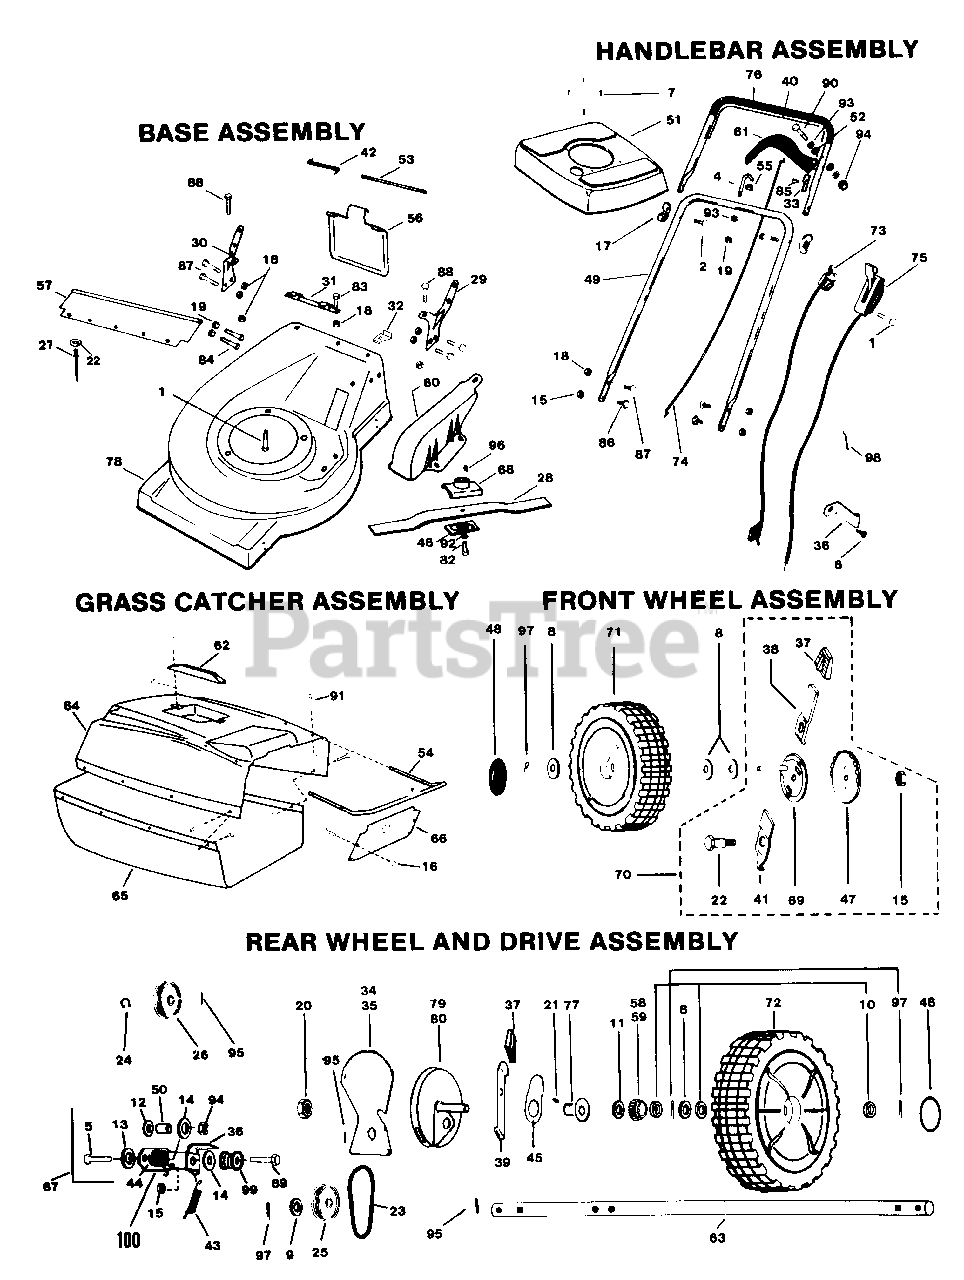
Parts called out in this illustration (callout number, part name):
1	Screw .375-16 x 1.00 Ind. Hex Hd.
2	Saddle Bolt .312-18 x .750
3	Screw .250-20 x .750
5	Screw .250-20 x 1.250
6	Screw #10-32 x .375
7	Screws-Engine Shroud
15	Nut .375-16 Keps
16	Nut #10-32 Keps
18	Nut .312-18 Keps
19	Nut .250-20 Keps
21	Key-Drive
22	Shoulder Bolt .375-16 x 1.00
24	Retaining Ring
25	Driven Pulley
26	Drive Pulley
27	Pop Rivet
28	Blade-21"
29	Lug-Handle-LH.
30	Lug-Handle-RH.
31	Attaching Bracket
32	Brkt.-Attaching
33	Brkt.-Bail Stop
34	Plate-Rear-RH.
35	Plate-Rear-LH.
36	Retainer .250
40	Bail Lever
42	Spring Door
43	Drive Spring
44	Idler Return Spring
46	Retainer Plate
49	Handle-Lower
50	Idler Bracket Bushing
51	Shroud-Engine
52	Spacer-Clutch Handle
53	Rear Door Hinge
54	Support Rod
55	Rope Guide
56	Rear Door
57	Drag Pan-20"
58	Drive Gear-LH.
59	Drive Gear-R.H
60	Belt Cover
61	Clutch Handle
64	Top-Catcher
65	Bottom-Catcher
66	Back-Catcher
67	Idler Assembly
68	Blade Adaptor
69	Plates Pin
70	Height Adj. Ass'y.
71	Wheel Ass'y.-8"
72	Wheel Ass'y.-10"
73	Zone Restart Cable
74	Traction Control Cable
75	Throttle Control
76	Handle-Upper
77	Support Hubs Brg. Ass'y.
79	Dust Cover-LH.
80	Dust Cover-RH.
81	Capscrew, Hex HD. .250-20 x .50
82	Capscrew, Hex HD. .375-24 x 1.250
83	Bolt, Carriage .250-20 x .50
84	Bolt, Carriage .250-20 x .625
85	Screw #10-32 x.50
86	Capscrew, Hex HD. .375-16 x .750
87	Bolt, Carriage .312-18 x .750
88	Capscrew, Hex HD. .312-18 x .625
89	Capscrew, Hex HD. .250-20 x 2.00
90	Capscrew, Hex HD. .250-20 x 1.750
91	Screw #10-32 x .625
92	Lockwasher .375
93	Flatwasher .250
94	Nut, Lock .250-20
95	Roll Pin .187 x 1.00
96	Key, Woodruff .156 x .625
97	Pin, Cotter .125 x .750
98	Cable Tie
99	Idler Pulley Half
100	Idler Bracket
100	Decal-Engine Shroud
100	Decal-Model
100	Decal-21"
100	Decal-Clutch
100	Decal-Danger
100	Decal-Start & Stop
100	Decal-Caution
100	Decal-Simplicity
